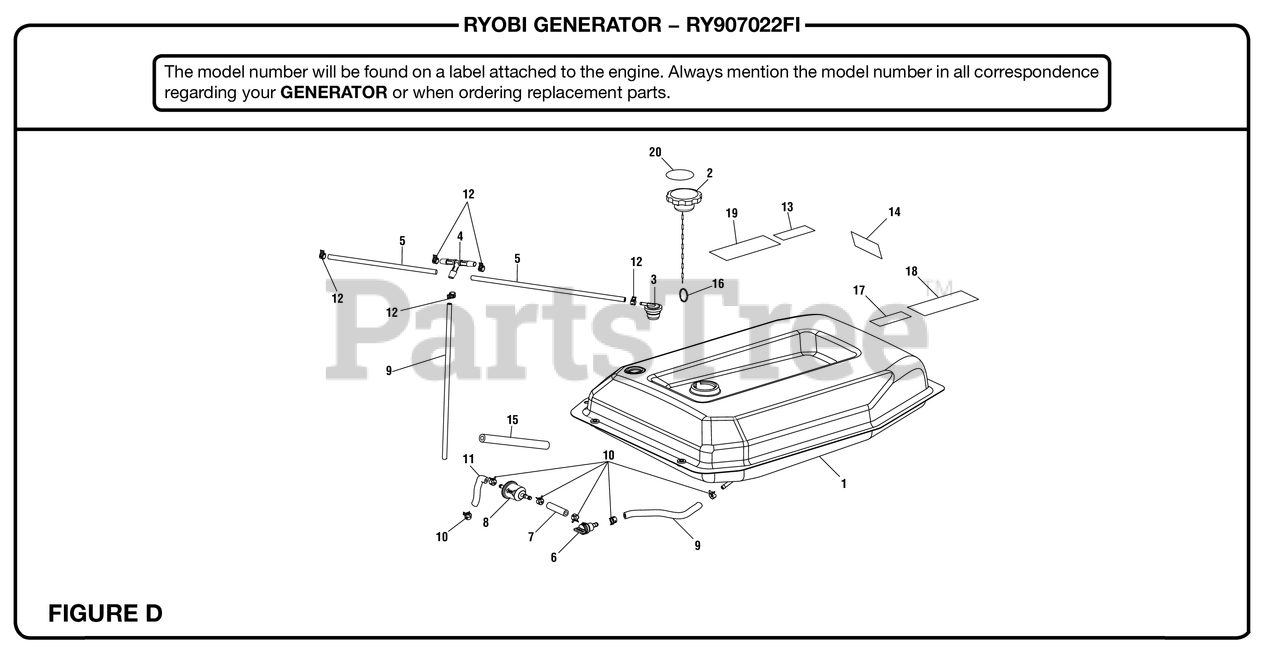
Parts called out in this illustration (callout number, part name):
1	Fuel System
2	Fuel Cap Assembly
3	Fuel Tank Vent Valve (PS905055SA)
4	Vapor Hose Tee Fitting
5	Vapor Hose (300 mm)
6	Fuel Shut Off Valve
7	Fuel Hose (60 mm)
8	Fuel Filter Inline (1/4 in.)
9	Fuel Hose (135 mm)
10	Fuel Line Clamp (1/2 in.).
11	Vapor Hose (500 mm)
12	Fuel Line Clamp (3/8 in.)
13	No E85 Label
14	CPSC (English) Label
15	Fuel Hose (210 mm)
16	Ring Clip
17	Fuel Stabilizer Label (French/Spanish)
18	Co Instruction & Warning Label
19	Warning Label
20	Remove Cap Fuel Stabilizer Label (English)
